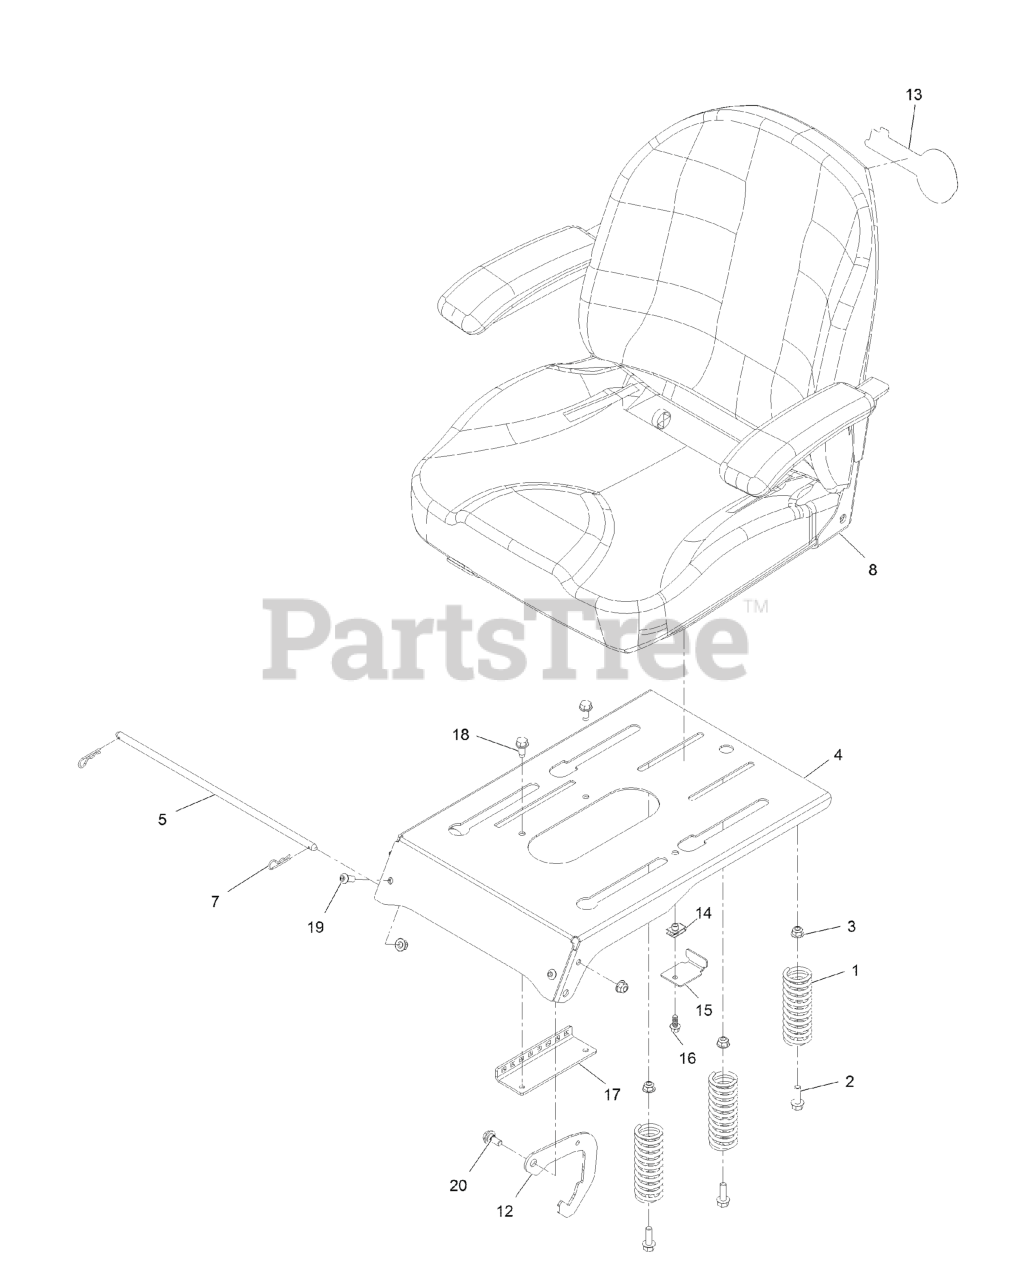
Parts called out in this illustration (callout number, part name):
1	SPRING-COMPRESSION
2	SCREW-HHF
3	NUT-HF, NI
4	PAN-SEAT, DELUXE
5	ROD-PIVOT, NARROW
7	PIN-COTTER
8	SEAT ASM, EXMARK
12	Seat Latch
13	DECAL-EXMARK LOGO
15	Bracket-Stop, Seat
16	SCREW-HHF
17	BRACKET-LATCH, SEAT
18	Screw-HWH 5/16-18 X 3/4 Tf
19	SCREW-HSBH
20	SCREW-SHOULDER
